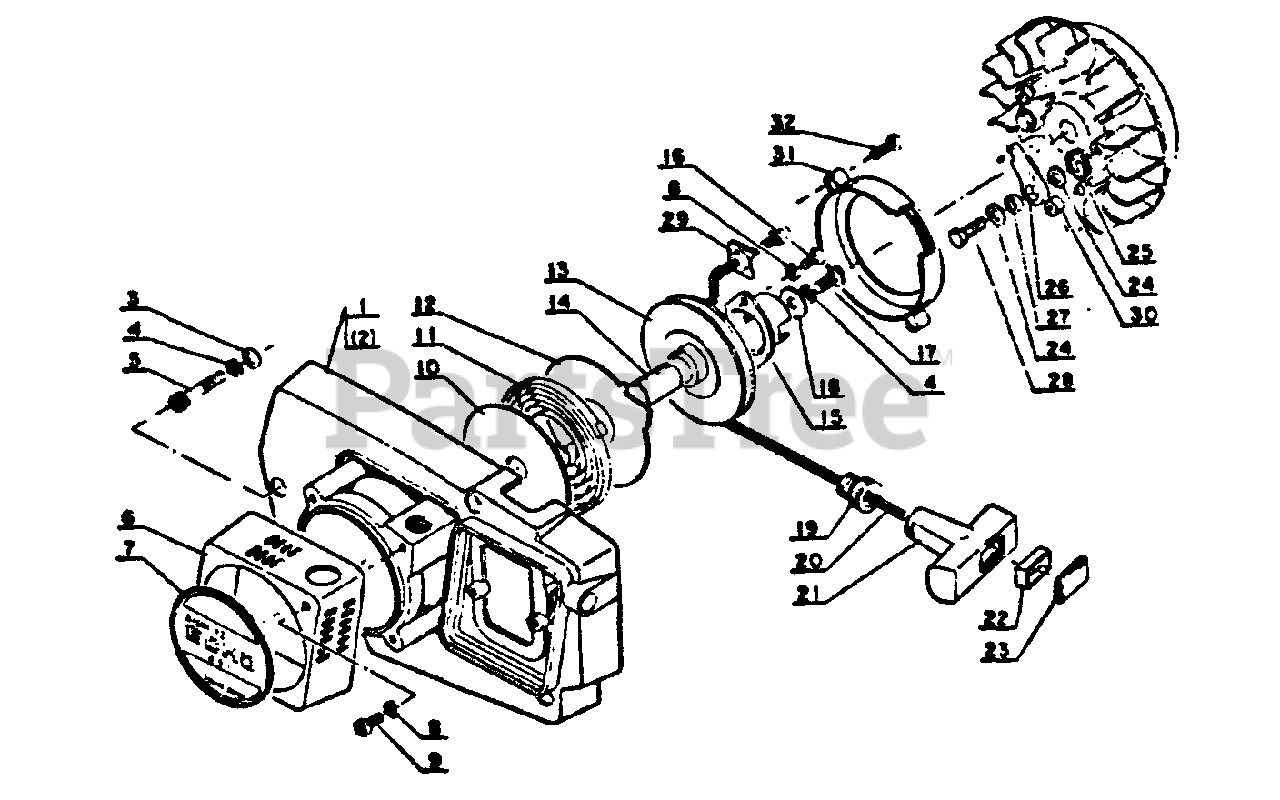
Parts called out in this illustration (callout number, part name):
1	CASE, STARTER
3	WASHER
4	WASHER, SPRING 5
5	BOLT - 5×25
6	FILTER, DEBRIS
7	NAME PLATE
8	WASHER, SPRING 4 MM
9	SCREW 4×8
10	PLATE, STARTER
11	SPRING, RECOIL
12	PLATE, STARTER
13	REEL, ROPE
15	CATCHER, PAWL
16	SCREW 4×10
17	BOLT - 5×12
18	WASHER 5.2×16×1.0
19	GUIDE, ROPE
20	ROPE, STARTER 4.0×950
21	GRIP, STARTER
23	COVER, HANDLE
24	WASHER, FLAT 5.5×10×0.8
26	PAWL, STARTER
28	BOLT 5×18
29	RETAINER, ROPE
31	COVER, DUST
32	SCREW 4×16
